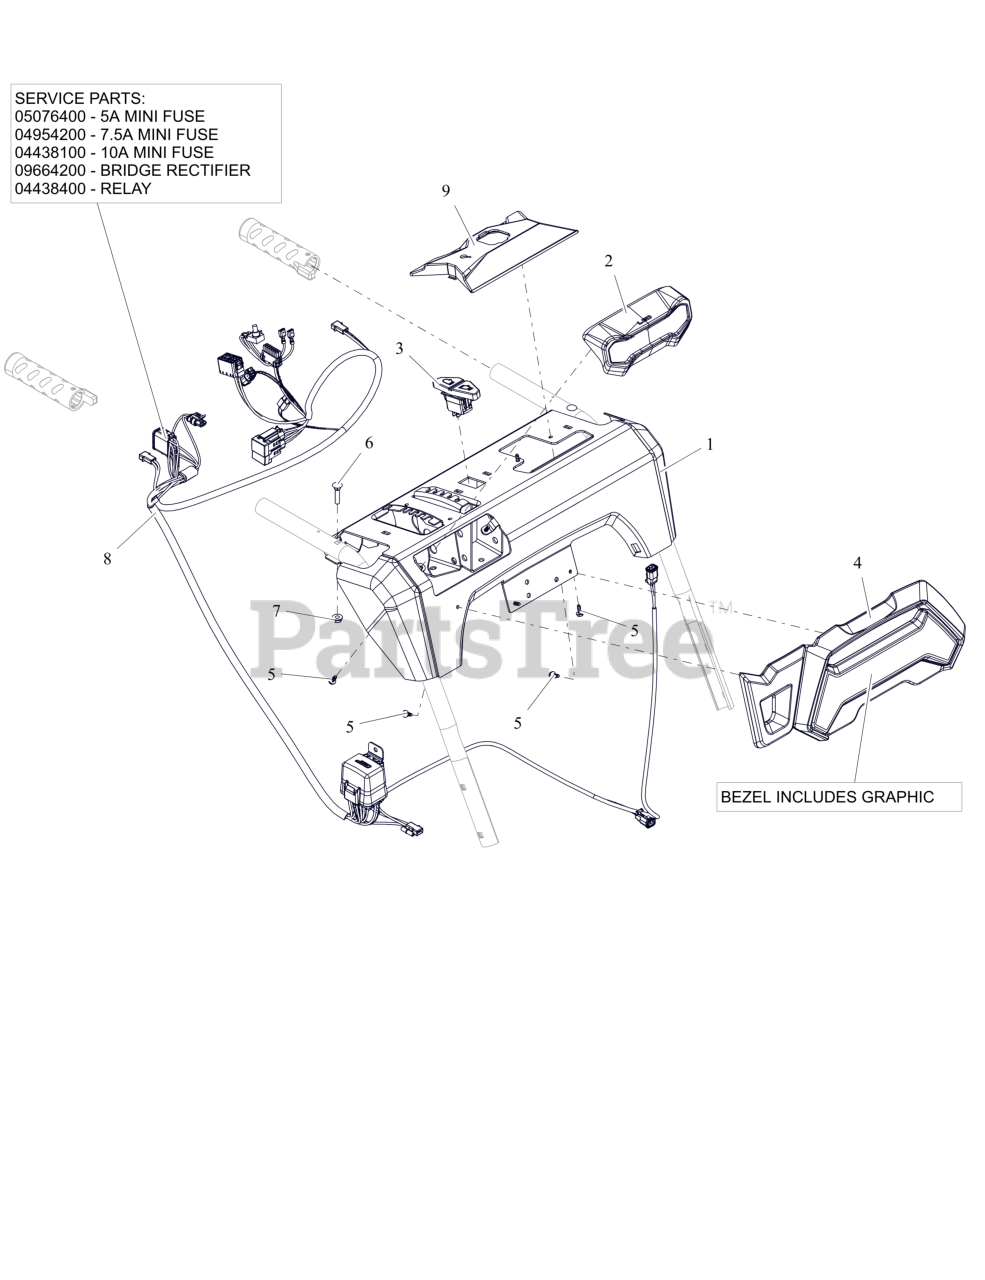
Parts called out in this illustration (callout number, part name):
1	PANEL, CONTROL-ECHUTE EFI W/DECALS
2	HEADLIGHT ASM- LED
3	SWITCH- ROCKER SPST-ON/OFF
4	BEZEL- LARGE - PLATINUM
5	SCR, PLASTIC #10X.50
6	BLT-RDHDXLSQNK.25-20X1.25 G5ZC
7	NUT-LK-CTR-FLG .25-20 ZC120
8	HARNESS-WIRE- LT HG EFI ECHUTE
8	FUSE, 5 AMP MINI-ATC
8	FUSE, 7.5 AMP MINI-ATC
8	FUSE,10 AMP MINI-ATC
8	RECTIFIER, BRIDGE
8	RELAY,MICRO5 TERML W/RESISTOR
9	BEZEL-OPERATOR-EFI ELEC CHUTE
